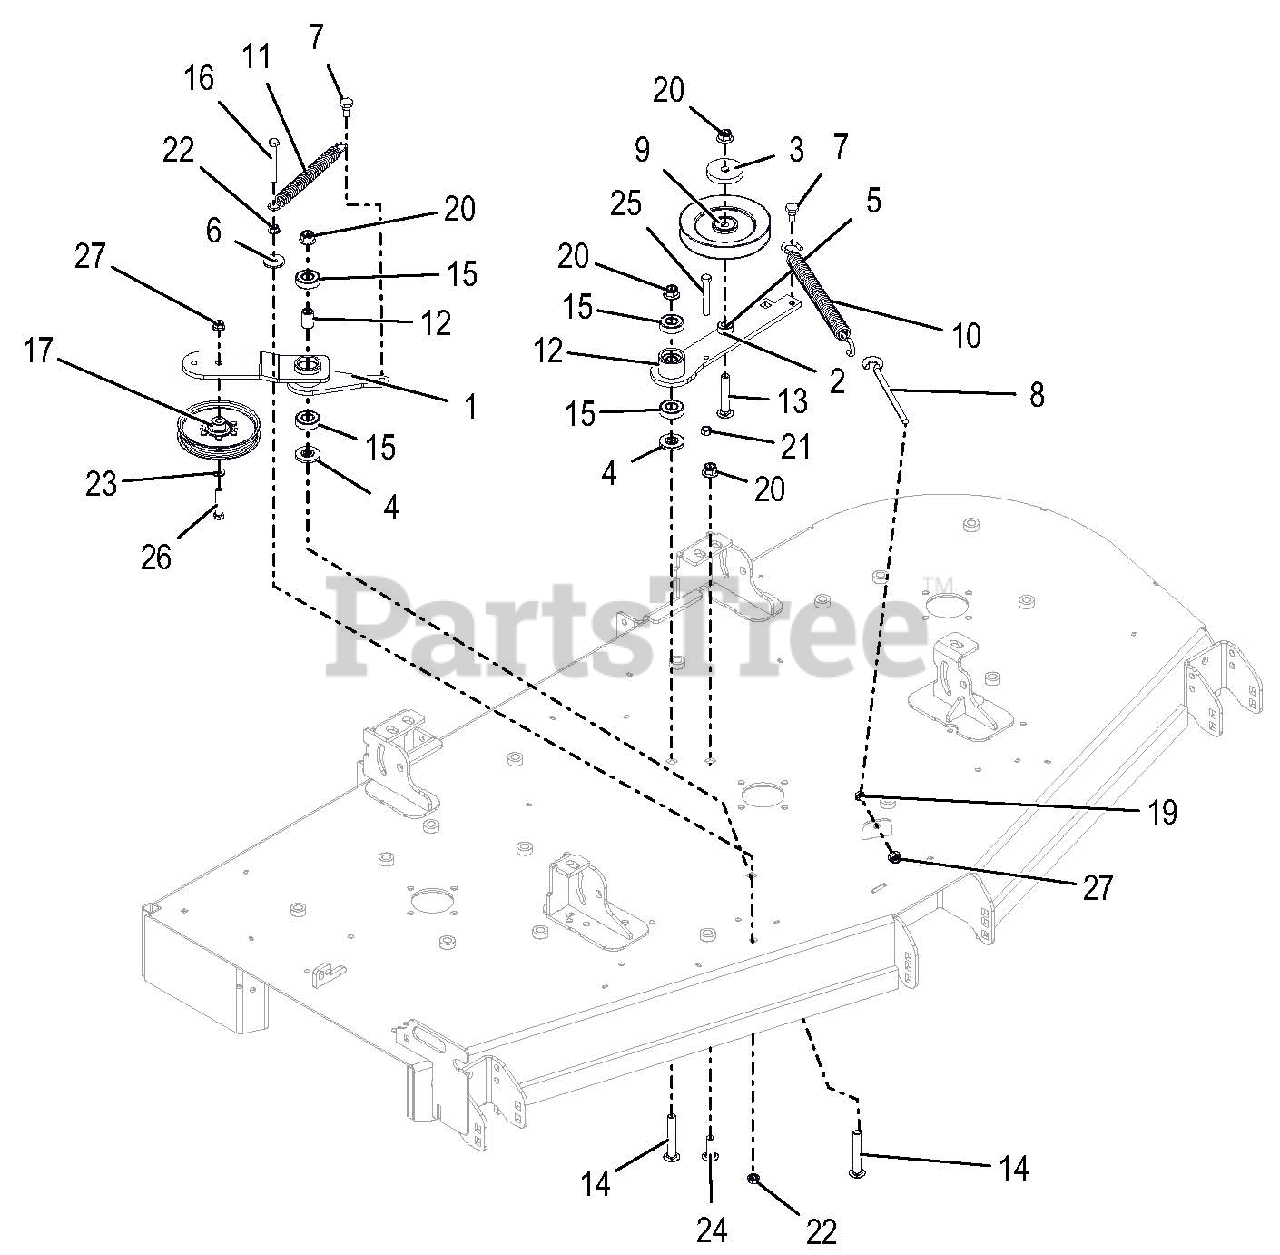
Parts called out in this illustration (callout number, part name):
1	DECK RH IDLER ARM WMT - BLK
2	DECK PTO IDLER ARM WMT - BLK
3	CAP, IDLER BEARING SEALING
4	SPACER, IDLER ARM
5	BSHG, SPCR .502X.997X.50 PM
6	WSHR-FL-STL .406X1.375X.135 YZ
7	BLT,SHLDR EP .38-16X.30 HEX YZ
8	BOLT, .38-16X6.00 .62 DIA EYE
9	SHV, .50"ID X 6.00"OD V-IDLER
10	SPRING, EXTENSION
11	SPRING, EXTENSION
12	SPACER .510 X .75 X 1.1485
13	@BLT-RDHDSQNK .50-13X3.00 G5YZ
14	BLT,RDHDSQSHNK.50-13X3.25 G5YZ
15	BRG-BALL .500X1.38X.437
16	@BLT-HEX .38-16X3.00 GR5 YWZC
17	PULLEY, FLAT IDLER
19	NUT-HEX-JAM .375-16 YWZC
20	@NUT-LK-NYL-FLG .50-13 YWZC
21	@NUT-HEX .38-16 YWZC
22	@NUT-SPNLK-FLG .375-16 YWZC
23	@WSHR-FL-STL.406X.812X.065 YWZ
24	BLT-RDHDSHSQNKFT.50-13X1.50 G5
25	@BLT-HEX .38-16X2.75 GR5 YWZC
26	@BLT-HEX .38-16X2.00 GR5 YWZC
27	@NUT-LK-NYL-FLG .38-16 YWZC
